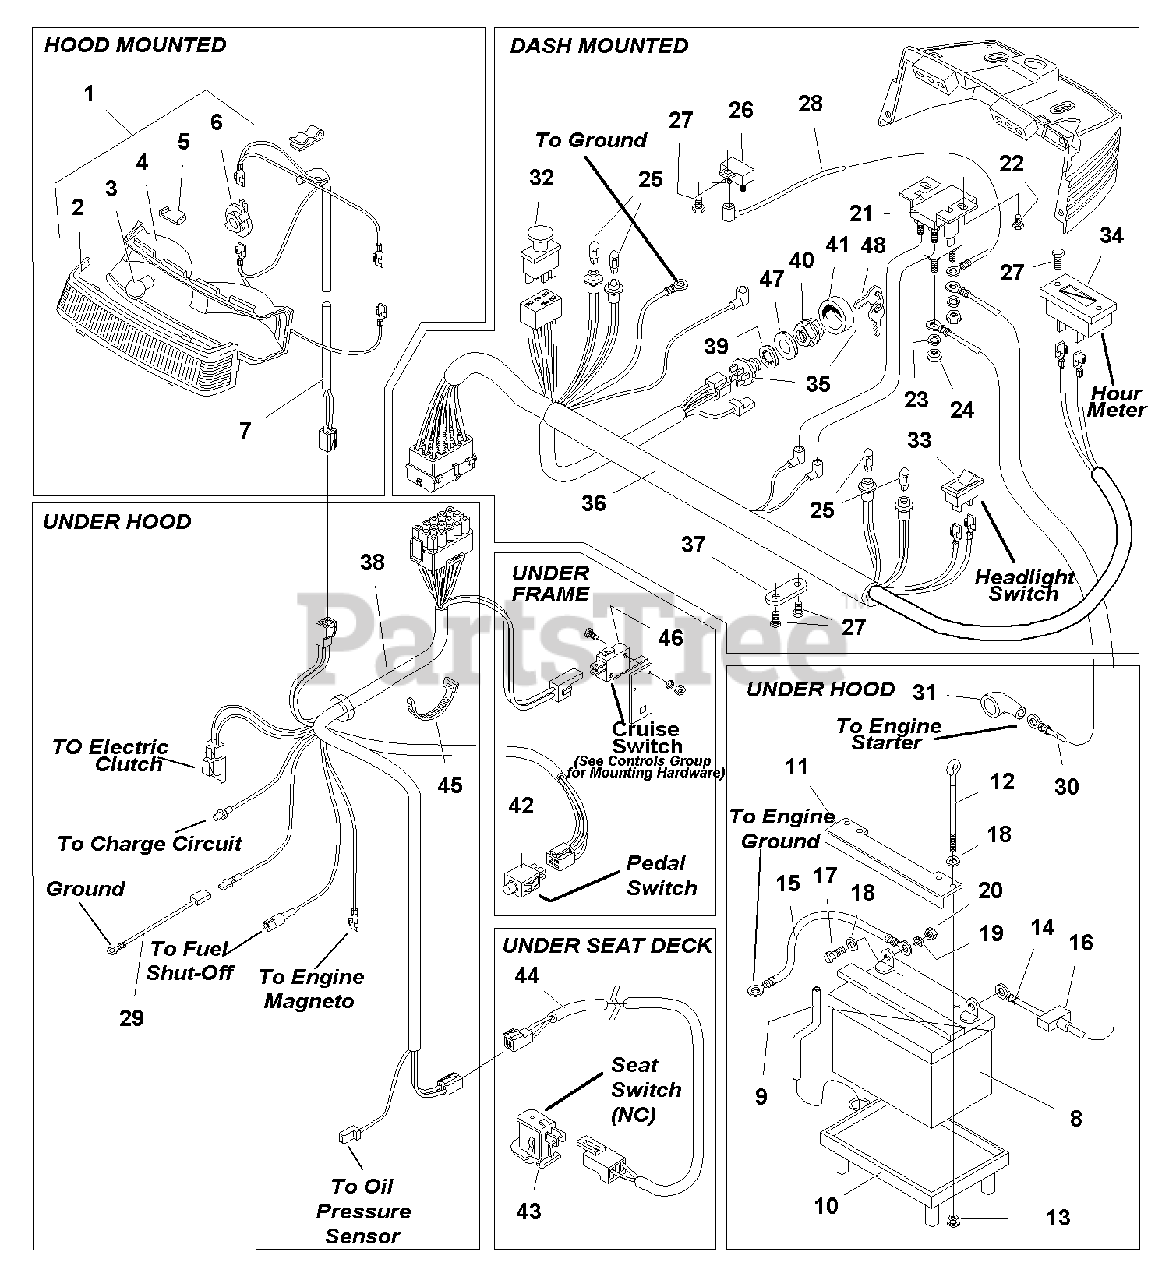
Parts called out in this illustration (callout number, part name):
1	HEADLIGHT ASSEMBLY, Complete (Includes Ref. Nos. 2-6)
2	LENS, Headlight
3	BULB, Headlight
4	BEZEL, Headlight
5	HEAT SHIELD
6	SOCKET, Bulb
7	WIRE ASSEMBLY, Headlight
8	BATTERY KIT
9	HOSE, Battery, Drain
10	TRAY, Battery
11	HOLD DOWN, Battery
12	ROD, Battery Hold Down
13	NUT, Plastic, 1/4-20
14	CABLE, Battery to Solenoid
15	CABLE, Battery to Ground
16	BOOT, Insulator
17	CAPSCREW, Hex Head, 1/4-20 x 3/4
18	WASHER, 1/4
19	WASHER, Lock, 1/4
20	NUT, Hex, 1/4-20
21	SOLENOID, 4-Pole, 12VDC
22	CAPSCREW, Hex Head, Plastite, 1/4-20 x 1/2
23	WASHER, Lock, 5/16
24	NUT, Hex, 5/16-24
25	BULB, Indicator Light
26	CIRCUIT BREAKER
27	CAPSCREW, Hex Head, Plastite, #8-16 x 1/2
28	WIRE ASSEMBLY
29	WIRE ASSEMBLY, Engine Ground
30	CABLE, Solenoid to Starter
31	COVER, Terminal
32	SWITCH, PTO Electric Clutch
33	SWITCH, Headlight
35	SWITCH ASSEMBLY, Ignition (Includes Ref. Nos. 39, 40, 41, 47 & 48)
36	WIRING HARNESS, Upper
37	STRAP, Wire Retainer
38	WIRING HARNESS, Lower
39	WASHER, Lock, Internal Tooth
40	NUT, Hex Flange, 5/8
41	COVER, Key Switch
42	SWITCH, Pedal
43	SWITCH, Seat (NC)
44	WIRE ASSEMBLY, Seat Switch
45	TIE, Self-Locking
46	SWITCH, Interlock
47	WASHER, 5/8
48	KEYS, Set of 2
